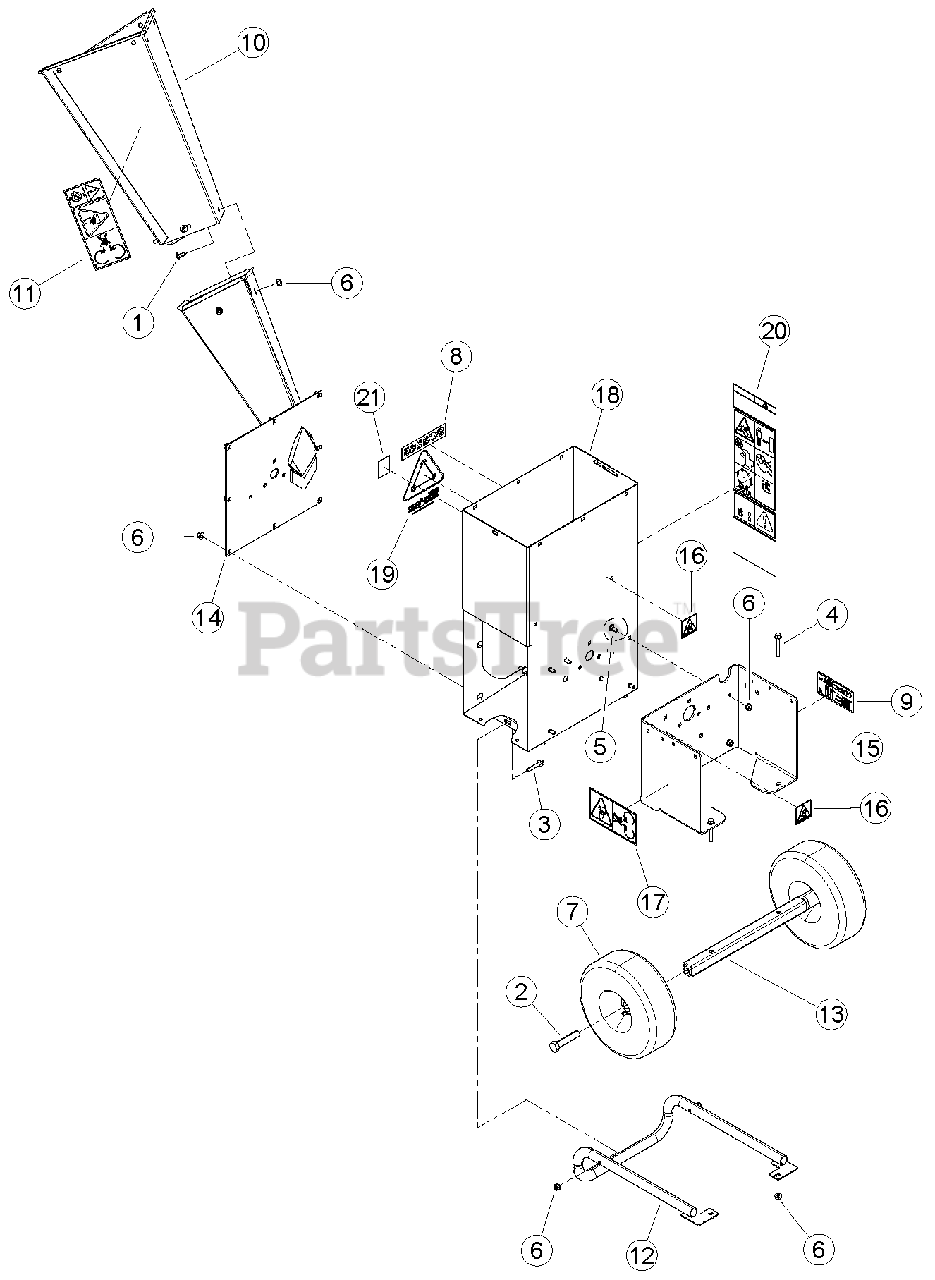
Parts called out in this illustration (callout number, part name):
1	BOLT, 5/16-18 X 3/4 CRG GR5 SN
2	BOLT, 5/8 X 3 HEX GR5 ZP
3	BOLT, 5/16 X 1-3/4 FLANGE NC
4	BOLT, 5/16 X 2-1/4 FLANGE NC
5	BOLT, 5/16 X 3/4 CRG GR5 NC ZP
6	NUT, 5/16-18 NYLOCK-FLANGE
7	ASSEMBLY, WHEEL 410/350-4
8	DECAL, MODEL SC3342
9	DECAL, SC3342 CE INFO AND NOISE
10	ASSEMBLY, 3" CHIPPER CHUTE EXTENSION
11	DECAL, 3" CHIPPER CHUTE
12	WELDMENT, SUPPORT LEG LONG
12	WELDMENT, SUPPORT LEG SHORT (SC3206XE ONLY)
13	WELDMENT, AXLE 3 IN CHIPPER
14	WELDMENT, CHIPPER CHUTE
15	ASSEMBLY, BASE 3 IN CHIPPER SERVICE PART
16	DECAL, SHIELD DANGER ISO
17	DECAL, BLADE DANGER ISO
18	ASSEMBLY, 3" C/S WIDE BODY SERVICE PART
18	ASSEMBLY, 3" C/S NARROW BODY SERVICE PART (SC3206XE ONLY)
19	DECAL, SHRED IT
20	DECAL, 3" CHIPPER BODY SIDE
21	DECAL, ECHO BEARCAT QR CODE
